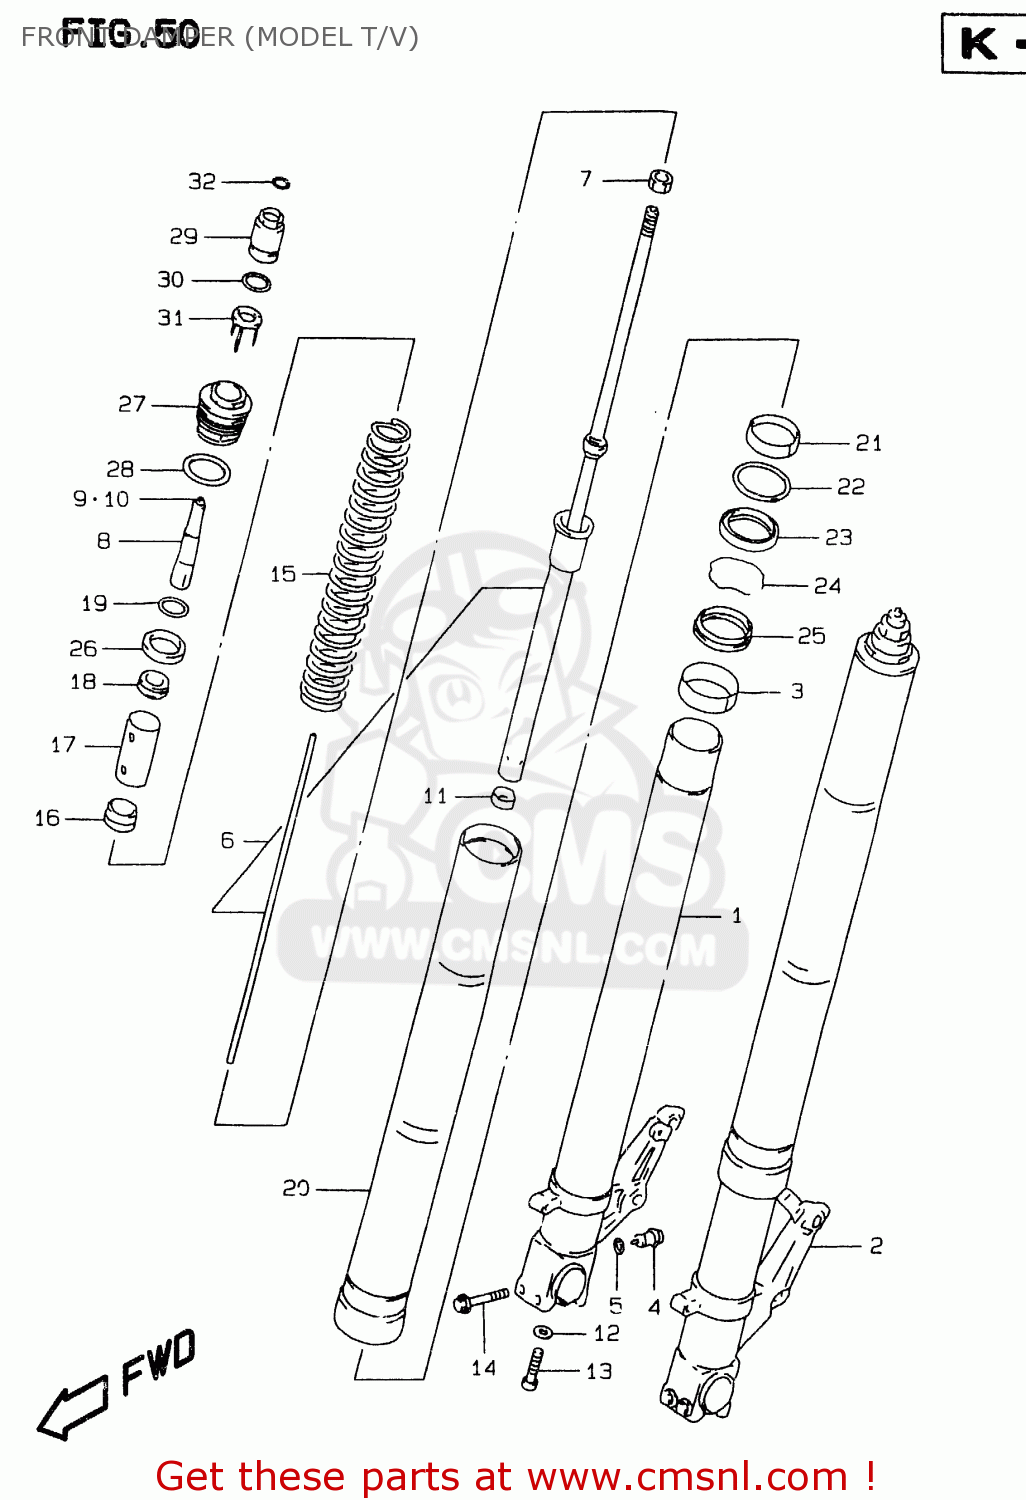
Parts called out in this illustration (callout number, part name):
1	TUBE,INNER,R
2	TUBE,INNER,L
3	BUSH,SLIDE
4	PIECE,ADJUST
5	O-RING (D:2.4 ID:13.8)
6	ROD,FRONT DAMPER
7	NUT
8	CASE,ADJUSTER
9	PIECE,ADJUST
10	O RING(D:1.9,ID:3.8)
11	PLATE,CENTERING
12	WASHER(10X15X1.5)
13	BOLT
14	BOLT
15	SPRING,MAIN
16	JOINT,SPRING
17	COLLAR,SPRING
18	GUIDE,SPRING UPR
19	GUIDE,SPRING
20	TUBE,OUTER
21	BUSH,GUIDE
22	SPACER,SEAL
23	SEAL,OIL
24	CIRCLIP,FORK OIL SEAL
25	SEAL,DUST
26	RUBBER,SEAT
27	BOLT,FORK
28	O RING,FORK BOLT
29	ADJUSTER,SPRING
30	O RING
31	PLATE,SPRING ADJUSTER
32	RING,STOPPER
